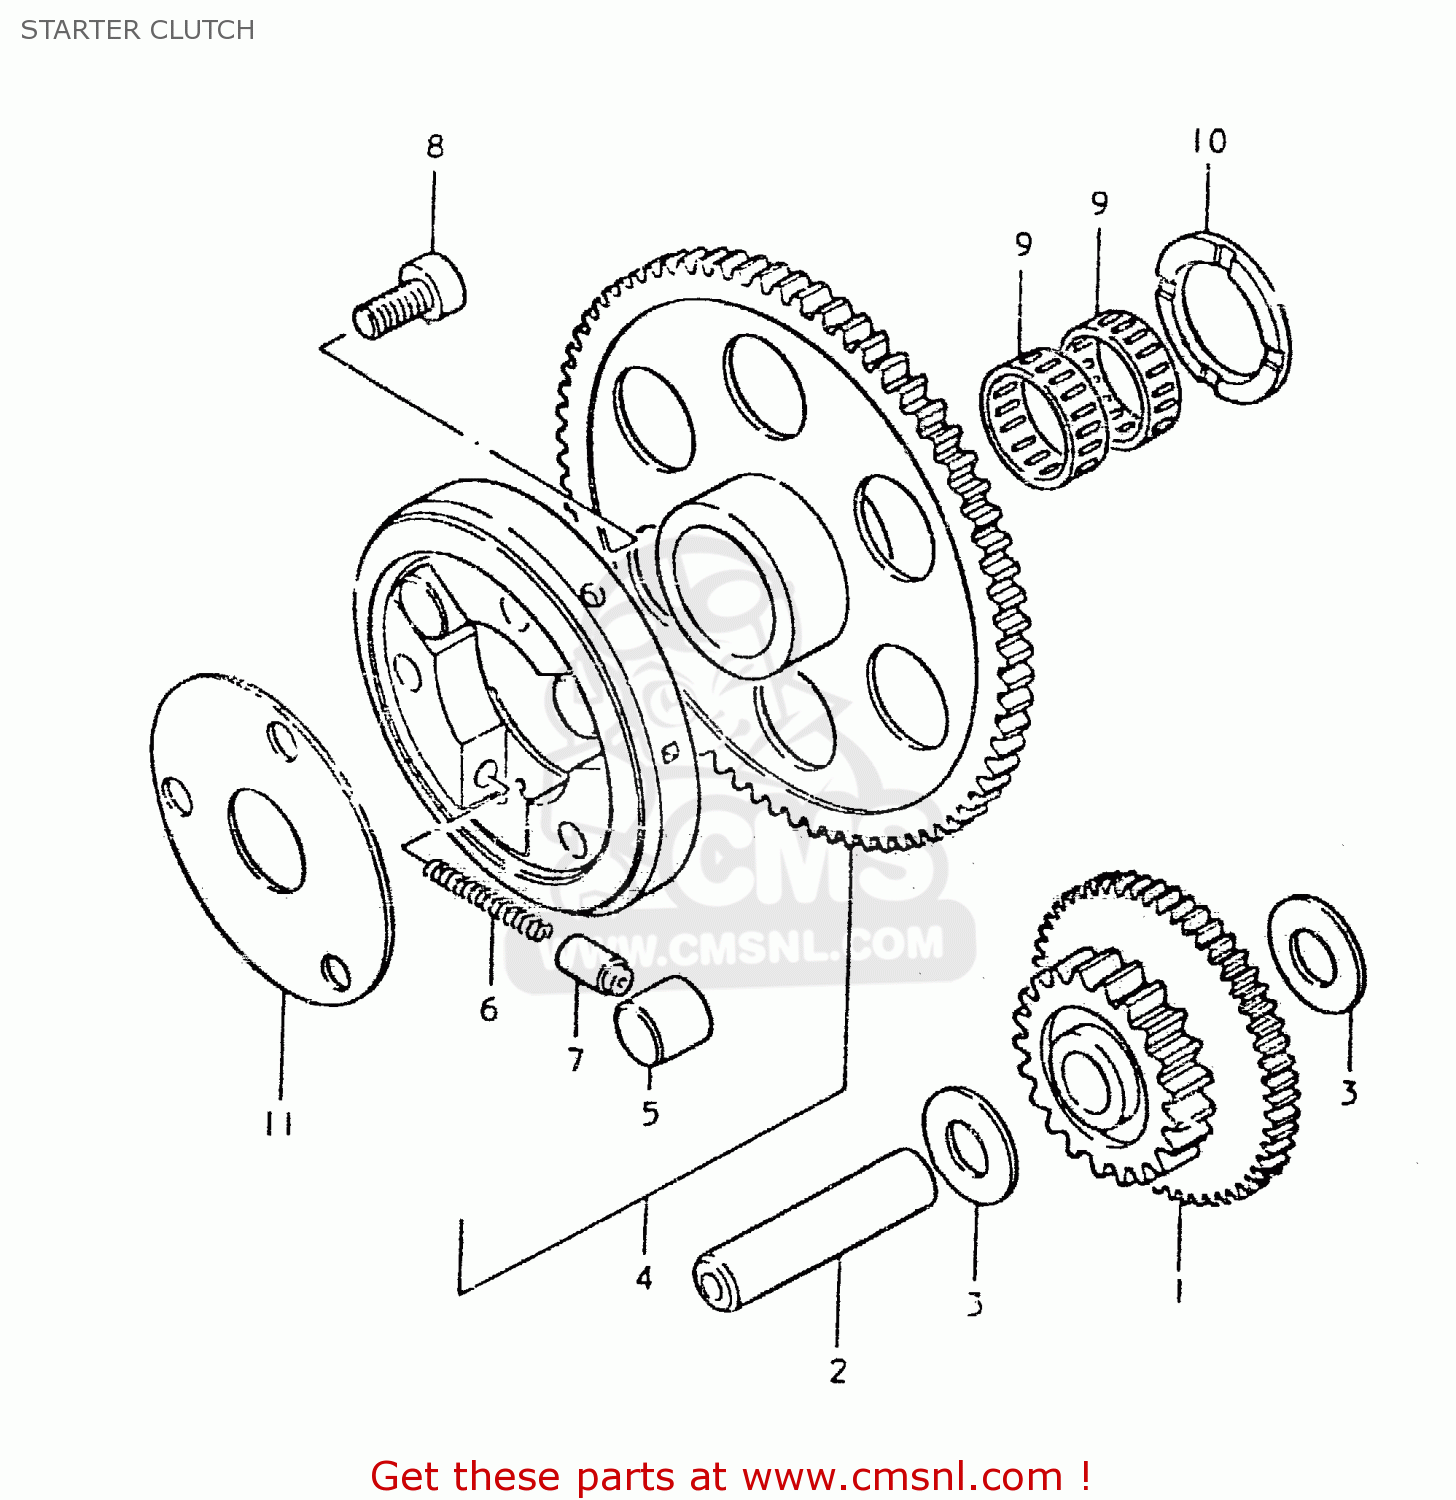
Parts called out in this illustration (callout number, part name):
1	GEAR,STARTER IDLE
2	PIN(7.4X13X56)
3	WASHER(13.3X25X0.85)
4	CLUTCH SET,STARTER
5	ROLLER(15X13)
6	SPRING
7	PIECE,PUSH
8	BOLT
9	BEARING
10	WASHER(25X38X2.5)
11	SHIM,STARTER CLUTCH HUB
